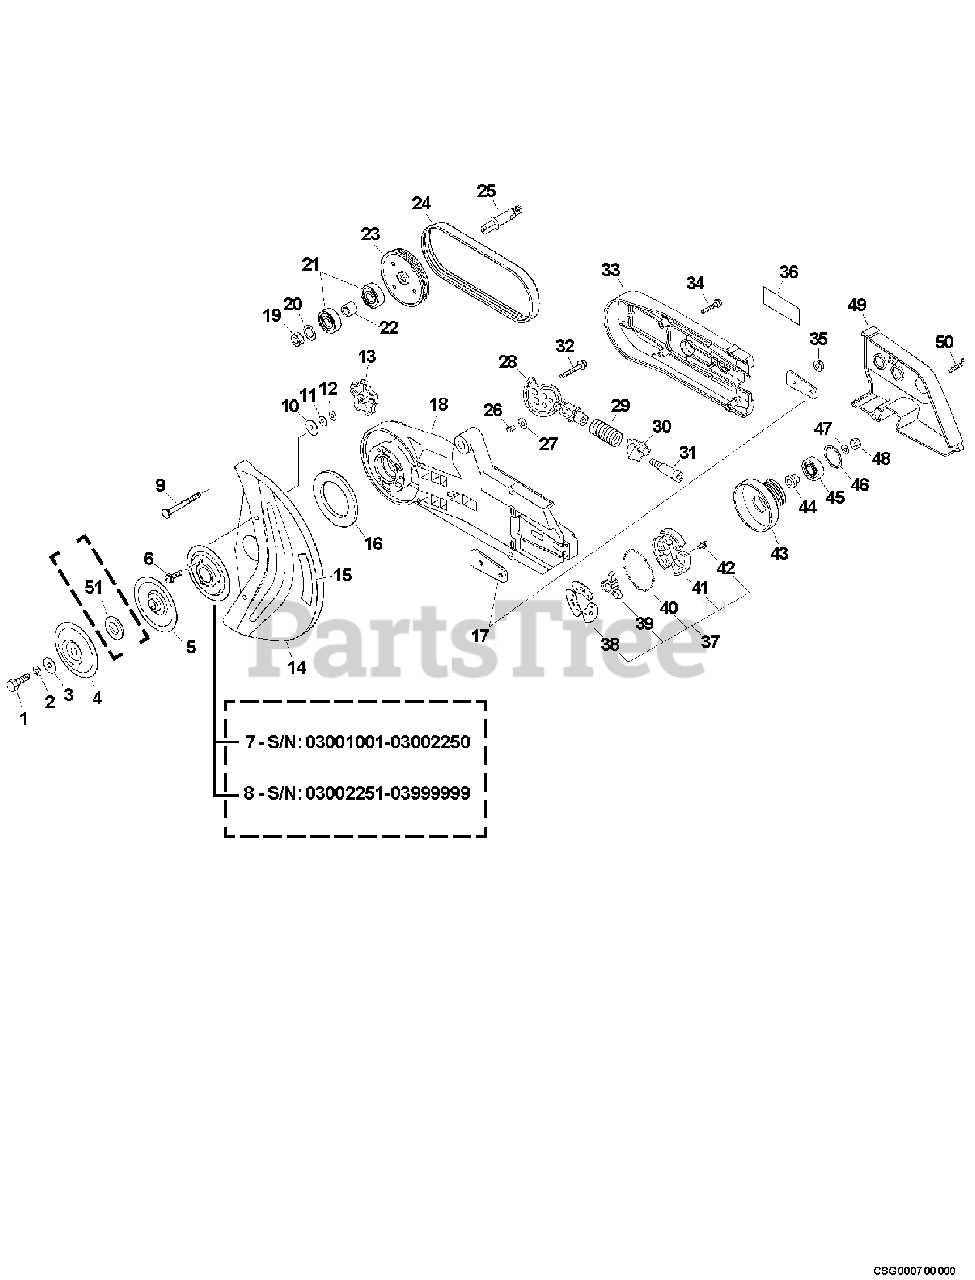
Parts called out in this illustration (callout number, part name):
2	WASHER, SPRING 10
4	FLANGE, CUTTER
5	FLANGE, CUTTER
6	SCREW - 4×10
7	PLATE
10	WASHER - 8
11	WASHER 8.5×16×1.2
12	WASHER, SPRING 8
13	KNOB, FASTENER
14	COVER, CUTTER
15	LABEL, CAUTION
17	SPACER, ARM
18	ARM, CUTTER
20	WASHER, SPRING 10
21	BEARING, BALL 6202 DDU
24	BELT
25	SHAFT, CUTTER
27	WASHER, SPRING 8.5×16×0.5
28	SHAFT, ARM ADJUST
29	SPRING, ADJUSTER
30	HOLDER, SPRING
32	BOLT 5×25
33	COVER, CUTTER ARM
34	SCREW 5×25
35	NUT, FLANGE M8×1.25
36	LABEL - ECHO
37	CLUTCH ASSY
38	PLATE, CLUTCH
39	BOSS, CLUTCH
40	SPRING, CLUTCH
41	SHOE SET, CLUTCH (3PCS)
42	BOLT 4×6
43	DRUM, CLUTCH
44	COLLAR - 10
45	BEARING, BALL 6001 DDU
46	RING, SNAP 28
48	NUT 8 LH
49	COVER, V-BELT
50	SCREW 5×25
51	WHEEL ADAPTER - 25 MM
